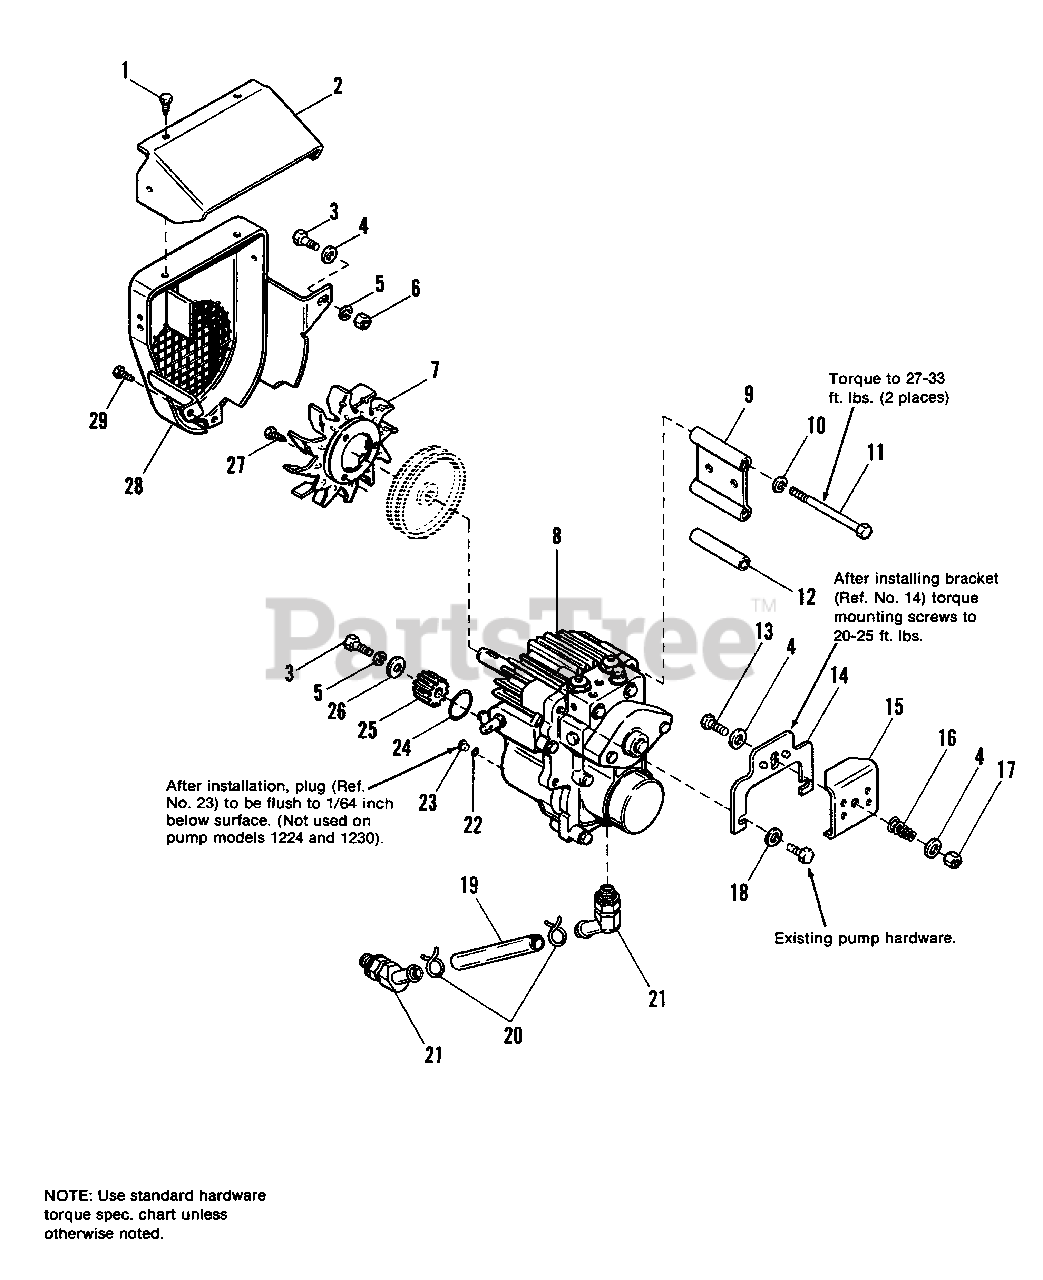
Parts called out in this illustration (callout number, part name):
1	SCREW, Self-Tapping, #10 x 3/8
2	DEFLECTOR, Shroud
3	CAPSCREW, Hex Hd., 5/16-18 x 3/4
4	WASHER, Plain, 5/16
5	LOCKWASHER, 5/16
6	NUT, Hex, Full, 5/16-18
7	FAN, Pulley
8	HYDROSTATIC PUMP& MOTOR UNIT (7112 & 7114)
8	HYDROSTATIC PUMP & MOTOR UNIT (7116, 7117 & 7119)
10	LOCKWASHER, 3/8
11	CAPSCREW, Hex Hd., 3/8-16 x 5
12	SPACER
13	CAPSCREW, Hex Hd., 5/16-18 x 1
15	LATCH, Release
17	LOCKNUT, Hex, 5/16-18
19	HOSE, Inlet
20	CLAMP, Hose
21	ELBOW, Hose Fitting
22	O-RING (If equipped)
23	PLUG (If equipped)
25	PINION, Motor Shaft
27	SCREW, Hex, Washer Hd., Taptite, 1/4-20 x 3/8
28	SHROUD ASSY., w/Screen
29	SCREW, Hex, Washer Hd., Taptite, 5/16-18 x 3/4
